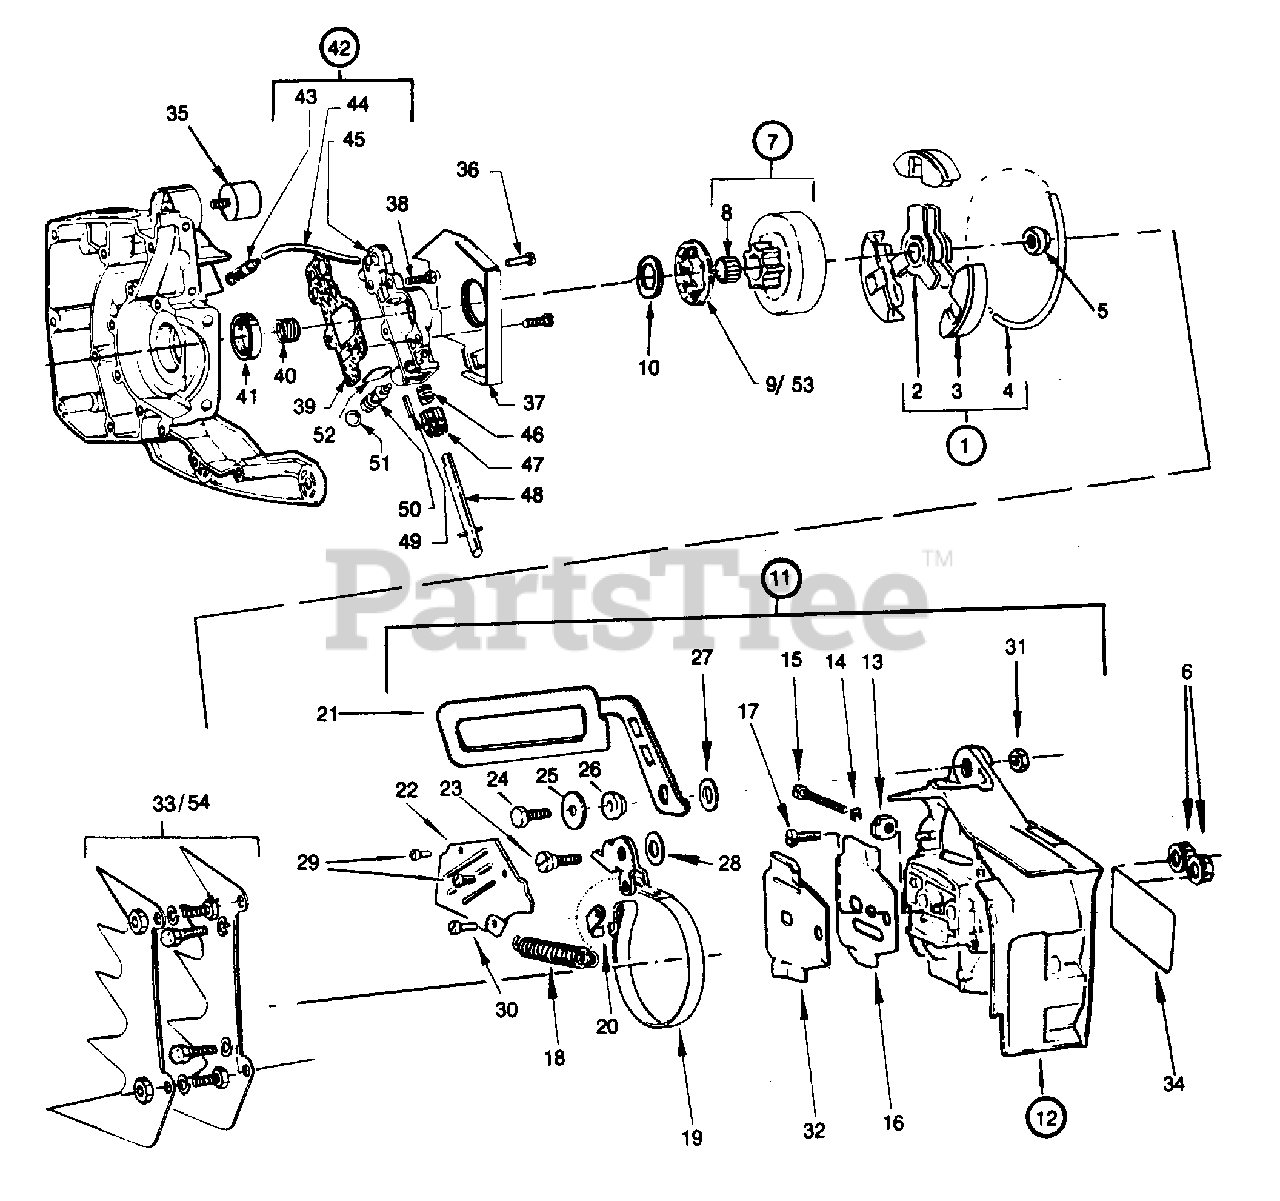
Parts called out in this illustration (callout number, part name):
1	Clutch Assy
2	Clutch Driver
3	Clutch Shoe (Wide)
4	Clutch Spring
6	Strut Nut
7	Clutch Drum & Bearing
9	3/8 7T Rim Segment
10	Thrust Washer
11	Brake Assy Complete
12	Clutch Cover & Tensioner
14	Retaining Ring
15	Screw - Chain Tension
16	Guide Plate (Outer)
17	Terminal Screw
18	Spring Chain Brake (White)
19	Cam/Band Assy
20	Locking Plate
21	Kickback Guard Assy
22	Cover Assy
23	Shoulder Bolt
24	Screw 1/4 - 20 X 1
25	Washer - Lever
29	Screw 10 - 24 X 2
30	Screw 10 - 24 X 3/8
32	Inner Guide Plate
33	Pivot Grip Kit (2/Kit)
34	Side Decal - Poulan Pro
35	Shock Absorber
36	Screw 10 - 24 X 1
37	Dirt Shield
38	Screw 10 - 24 X 3/4
39	Gasket - Oil Pump
40	Wire Worm
42	Oil Pump Assy Complete
43	Oil Pickup Assy
44	Inlet tube
45	Oil Pump Body
46	Plunger Spring
47	Gear - Oil Pump
48	Plunger Assy
49	Roll Pin
50	Adj. Screw
52	Seal - Oil Pump
53	Rim (404 - 7T)
54	Pivot Grip Kit (H)
